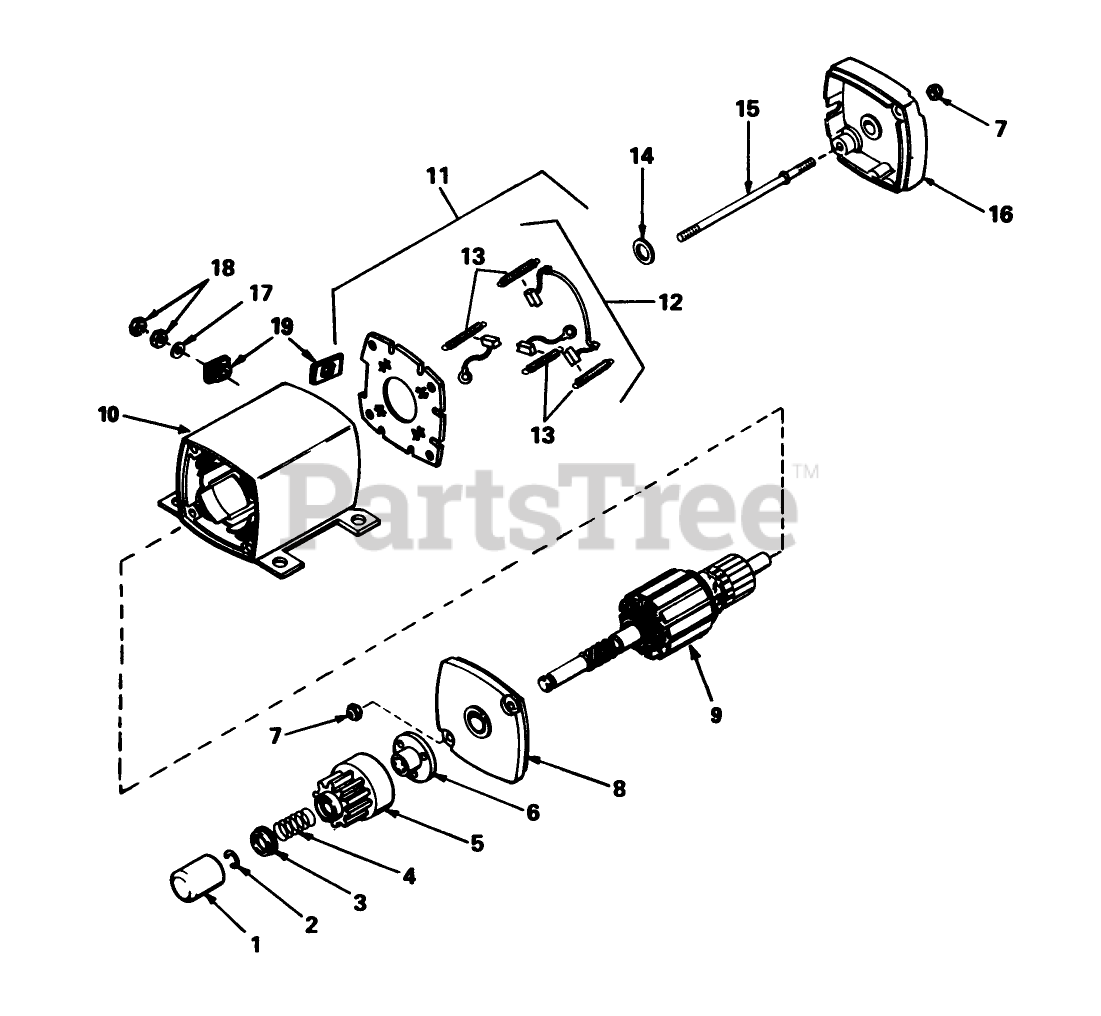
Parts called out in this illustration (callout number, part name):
1	Cover-Dust
2	Ring-Retainer
3	Retainer-Spring
4	Spring-Anti Drift
5	Gear
6	Nut Retainer (Incl. Ref. #2)
7	Nut-Lock
8	Cap Assy., Drive End
9	Armature
10	Housing
11	Card Assy., Brush (Incl. No. 12)
12	Brush Spring Kit (Incl. 4 pcs. of #13)
13	1545D SUP TO W/3256
14	Washer-Thrust
15	Bolt
16	2035A67 WIZARD W/34
17	Washer
18	Nut-Hex
19	Washer-Thrust
